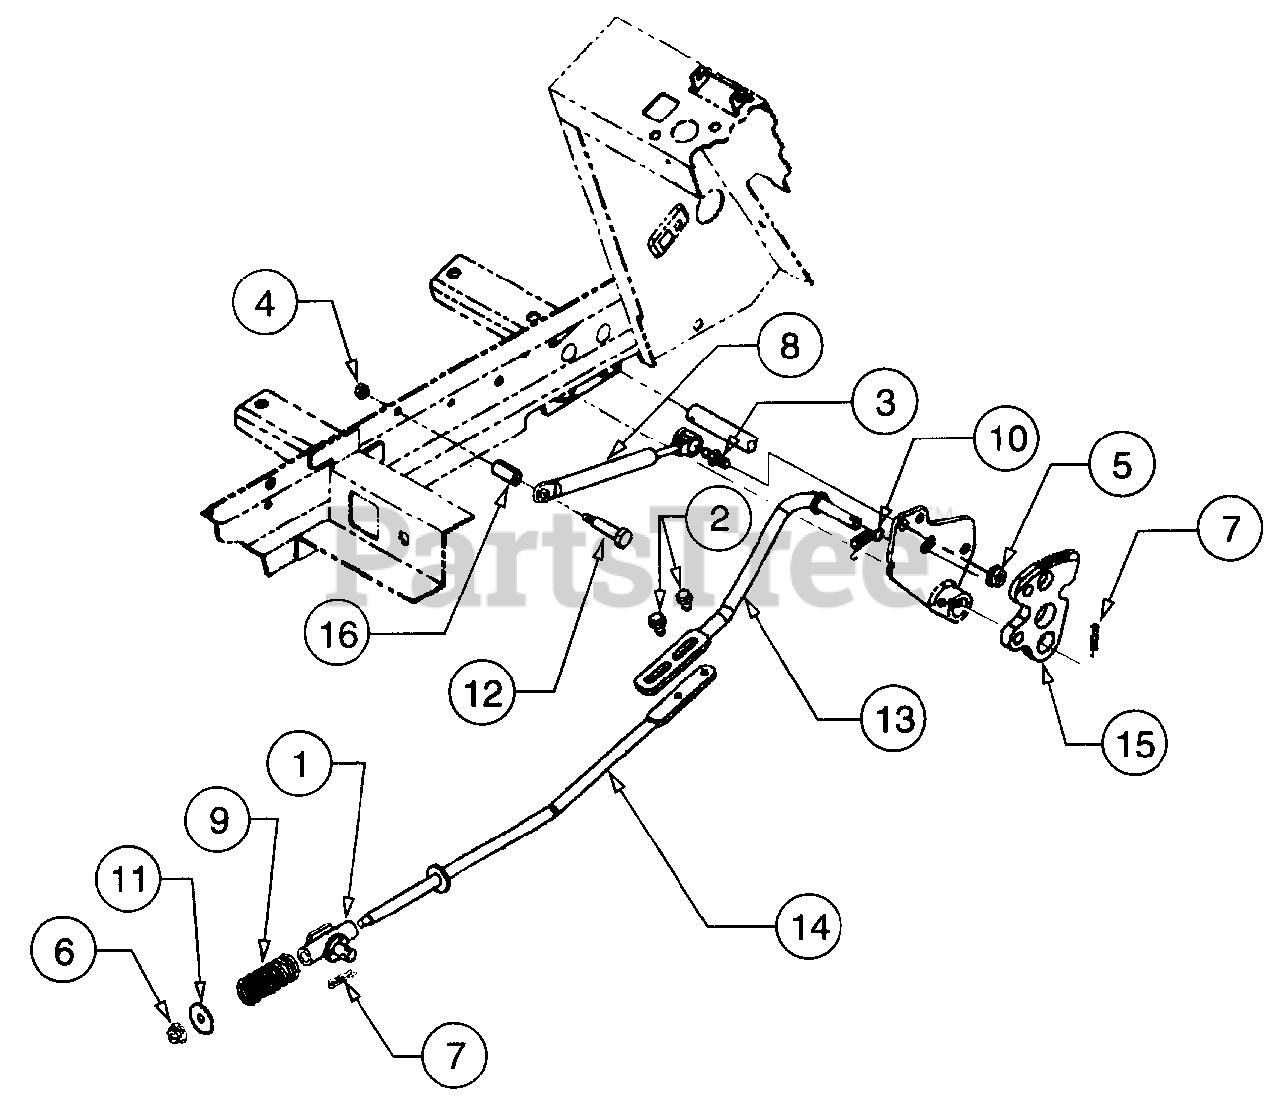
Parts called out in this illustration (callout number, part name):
1	Pivot Assembly
2	Screw, Hex Wash Hd Tapp 1/4-20 x .5
3	Screw, Ball, 5/16-18 x .56
4	Nut, Hex Sems, 1/4-20
5	Nut, Hex Flange Lock, 5/16-18 GR5
6	Nut, Hex Flange Lock, 1/4-20
7	Pin, Internal Cotter
8	Cylinder, Damper
9	Spring, Compression, .63 ID x 2.0 Lg
10	Spring, Extension, 3/8 OD x 1.44
11	Washer, Flat, .265 x 1.0 x .030
12	Bolt, Shoulder, .374 Dia x 1.375
13	Rod, Front Control
14	Rod, Rear Hydro Control
15	Plate, Cruise
16	Spacer, Split Tubing, .375 ID x 1.04
